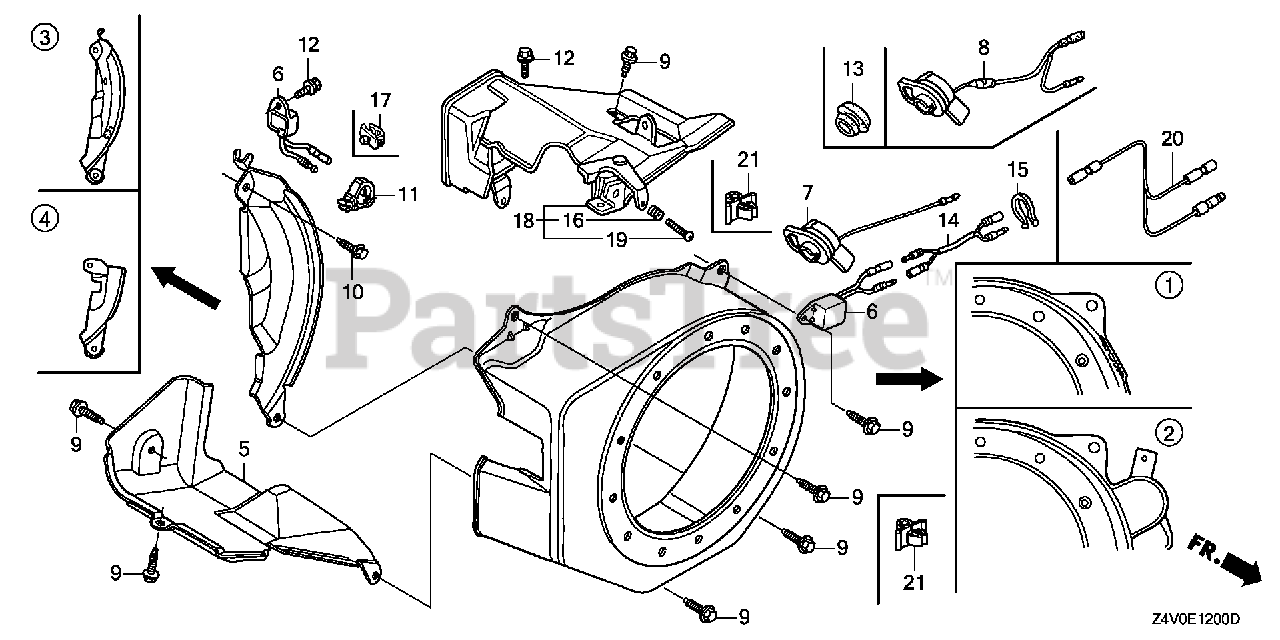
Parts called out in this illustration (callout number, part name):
2	COVER, FAN *NH1* (STARTER MOTOR) (BLACK) (NOT AVAILABLE)
4	PLATE, SIDE (STARTER MOTOR)
5	SHROUD
9	BOLT, FLANGE (6X12) (CT200)
